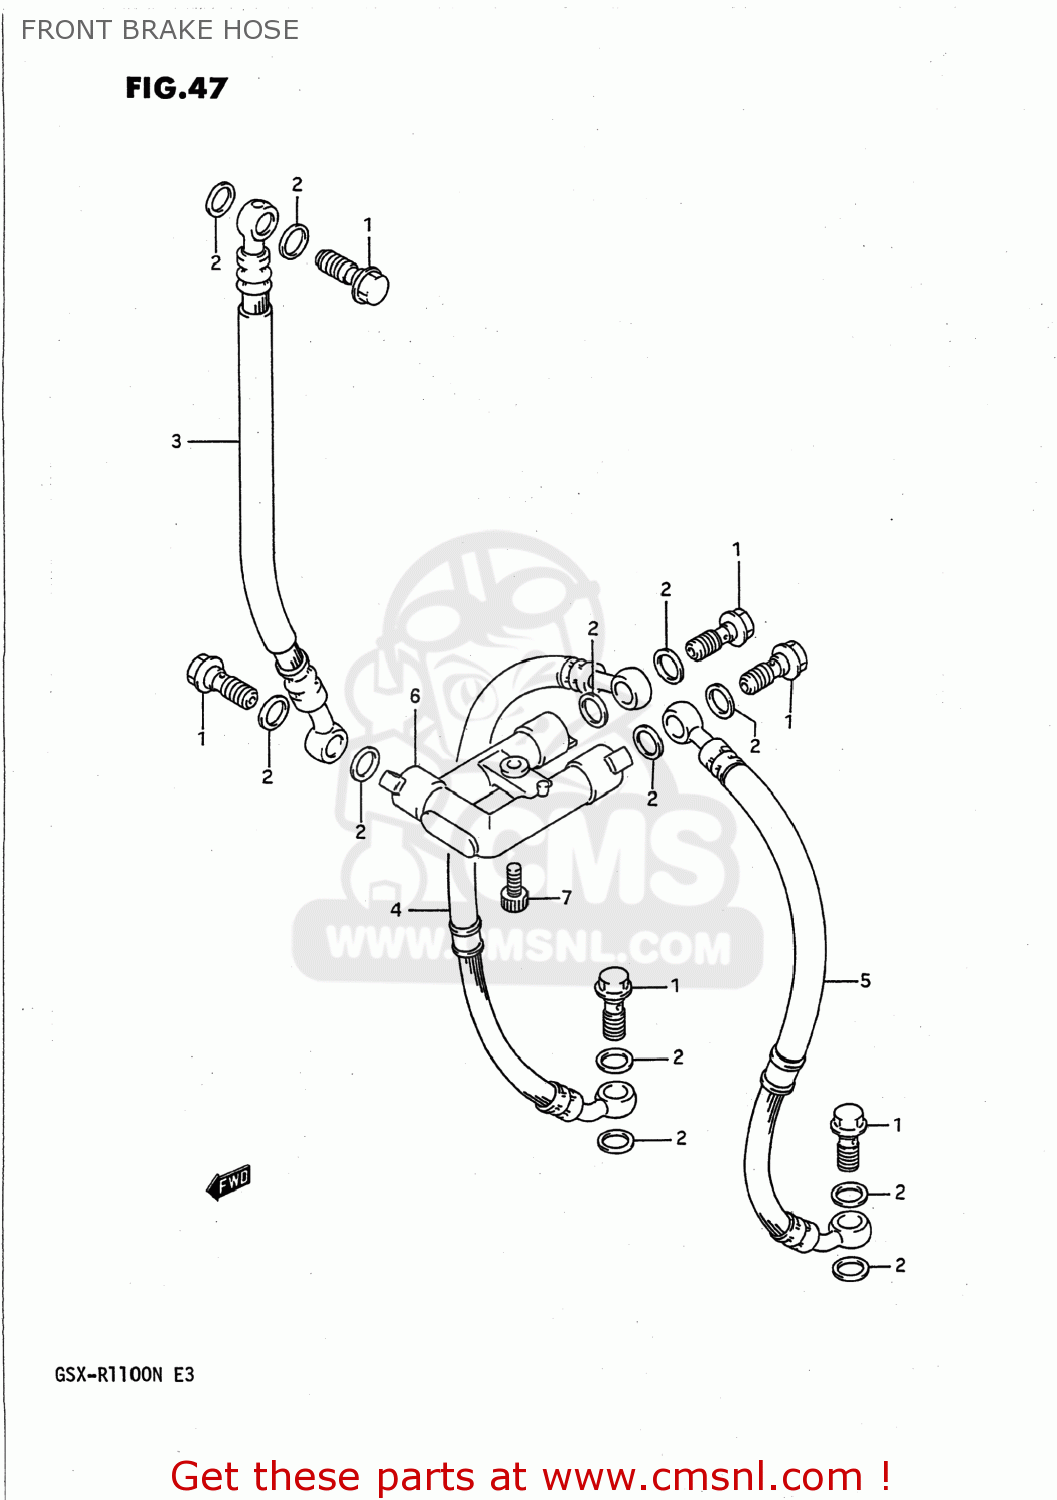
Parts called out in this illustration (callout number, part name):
1	BOLT UNION
2	WASHER(10X15X1.5)
3	HOSE,FRONT BRAKE
4	HOSE,FRONT BRAKE NO.2
5	HOSE,FRONT BRAKE NO.2
6	JOINT,BRAKE HOSE
7	BOLT
